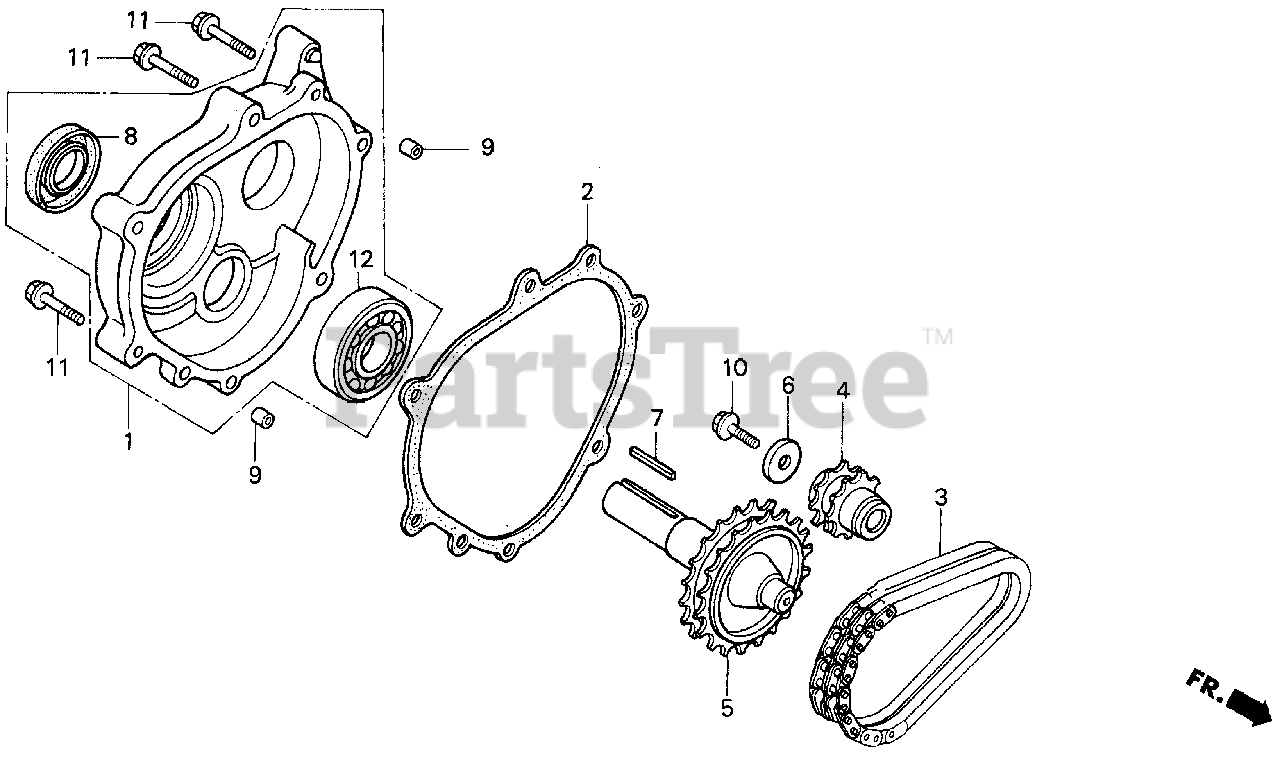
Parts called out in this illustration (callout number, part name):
1	COVER ASSY., CHAIN CASE
2	GASKET, CHAIN CASE COVER
3	CHAIN, P.T.O. DRIVE
4	SPROCKET, DRIVE (14T)
5	SHAFT, P.T.O. (28T) (L-TYPE)
6	WASHER (8MM)
7	KEY (7X7X33)
8	OIL SEAL (30X46X8)
9	PIN A, DOWEL (8X14)
10	BOLT, FLANGE (8X25)
11	BOLT, FLANGE (8X40)
12	BEARING, RADIAL BALL (6206)
